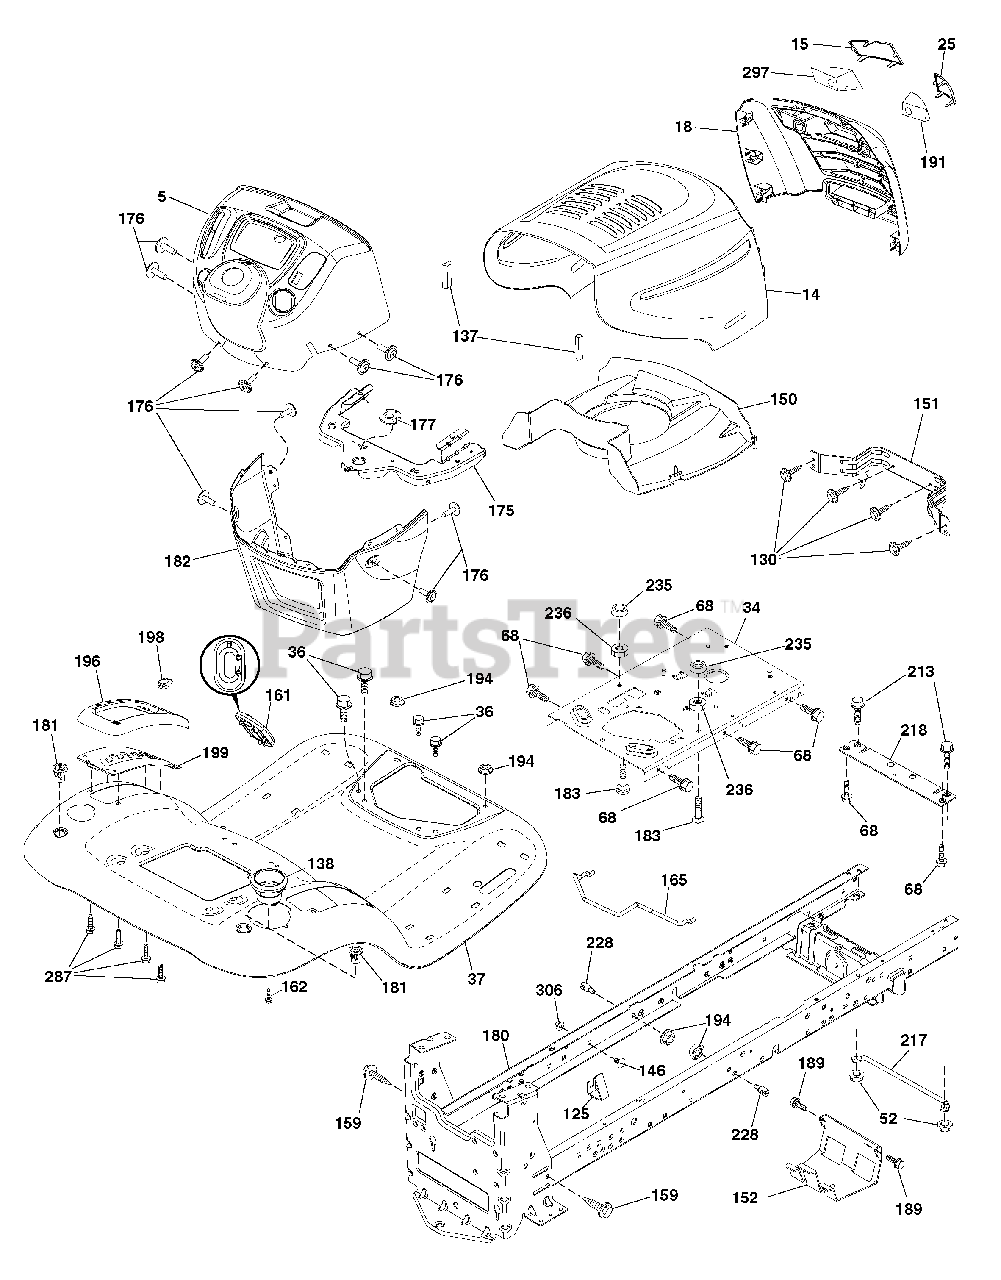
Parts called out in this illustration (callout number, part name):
15	Lens Grille LH
25	Lens Grille RH
34	Plate Engine
36	Screw 5/16-18 x 3/4
52	Nut Crownlock 5/16-18
68	Screw THDROL 5/16-18 x 1/2
125	Clip Fuel Line
130	Screw #10 x 0.750 BOS Thread
137	Bumper Hood
138	Cupholder
150	Duct Heat Hood
151	Bracket Pivot
152	Shield Browning/Debris
159	Screw 3/8-16 x 3/4
161	Window Fuel
162	Screw Hex Wsh Hi-Lo 1/4 x 1/2 unc
165	Support Tank Rear
175	Crossmember
176	Screw 10-24 x 5/8 Wshd Qdrx
177	Bushing Steering
180	Chassis
181	Bushing Mnt Fend Crgo Blk Tex
182	Dash Lower
183	Bolt Full Thd 5/16-18 x 1-1/4
189	Screw 5/16-18 x 3/4
191	Insert Lens Reflective RH
194	Nut Lock Hex Flange 5/16-18
196	Console Asm. Deck Lift
198	Indicator Deck Lift
199	Plate Deck Lift
213	Bolt Hex Hd. 5/16-18 unc x 3/4
217	Rod Pivot Hood
218	X-Piece Hood Stop
228	Stud Fastener
235	Spacer Fender
236	Nut Center Lock 5/16-18 unc
287	Screw 1/4-20 x 3/8
297	Insert Lens Reflective LH
306	Nut Lock
